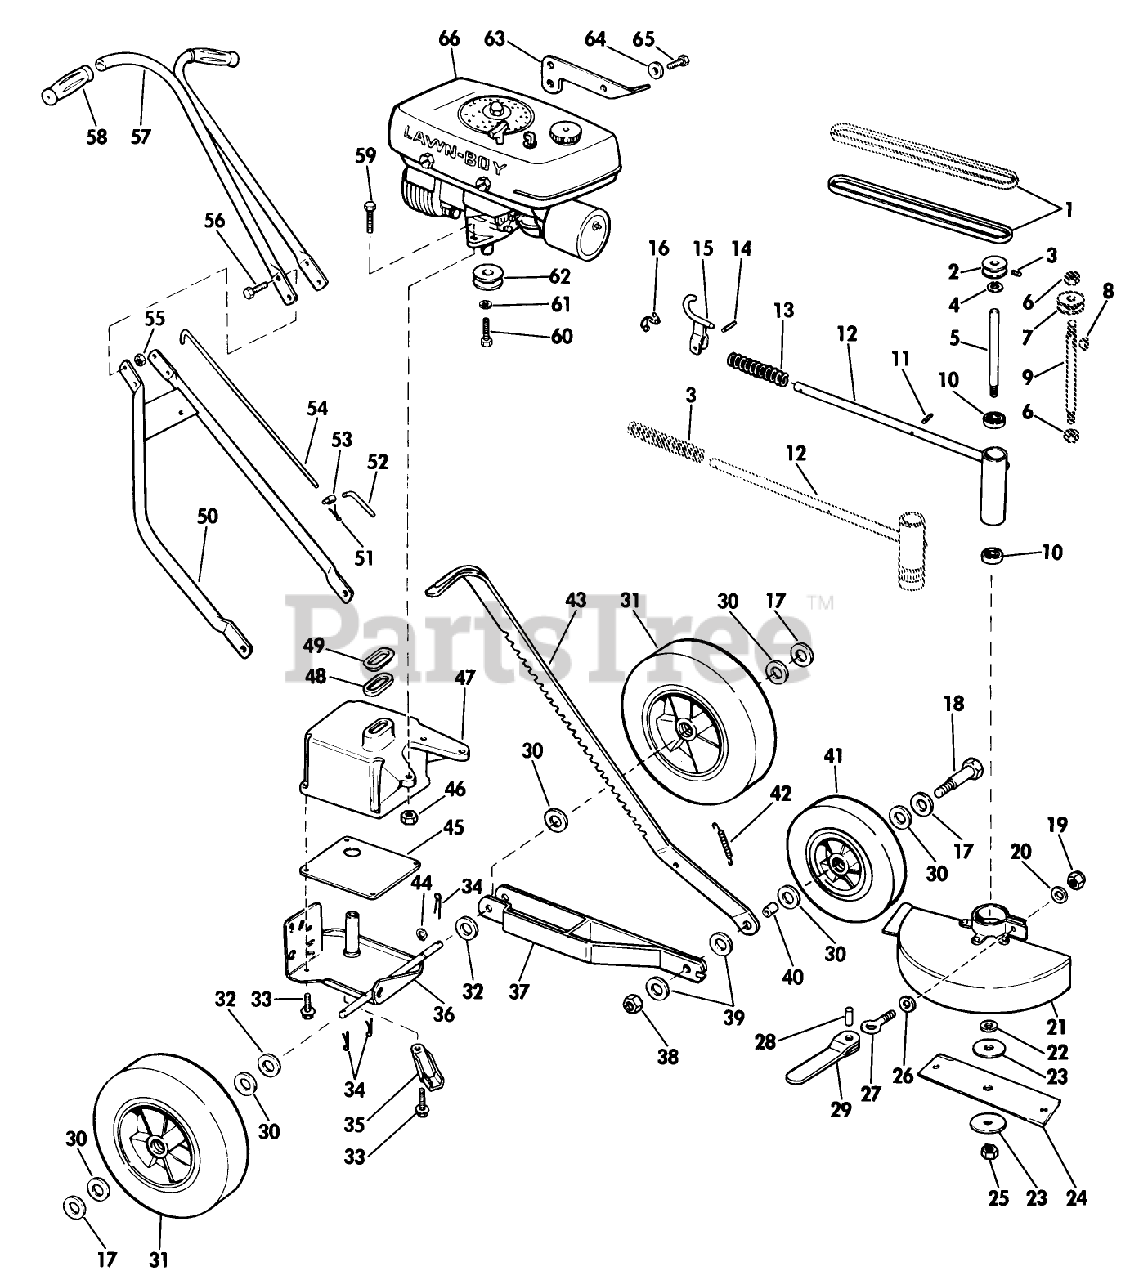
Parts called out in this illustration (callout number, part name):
12	Spindle Housing Pivot Assy.
17	SPACER
18	BOLT
22	WASHER
24	Blade-9"
26	WASHER WROUGHT
28	Roll Pin
30	WASHER
38	LOCKNUT
46	NUT-LOCK F
48	GASKET S
49	SLEEVE
56	SCREW
58	HANDLE GRIP
59	BOLT F
61	WASHER, LOCK
65	Screw
